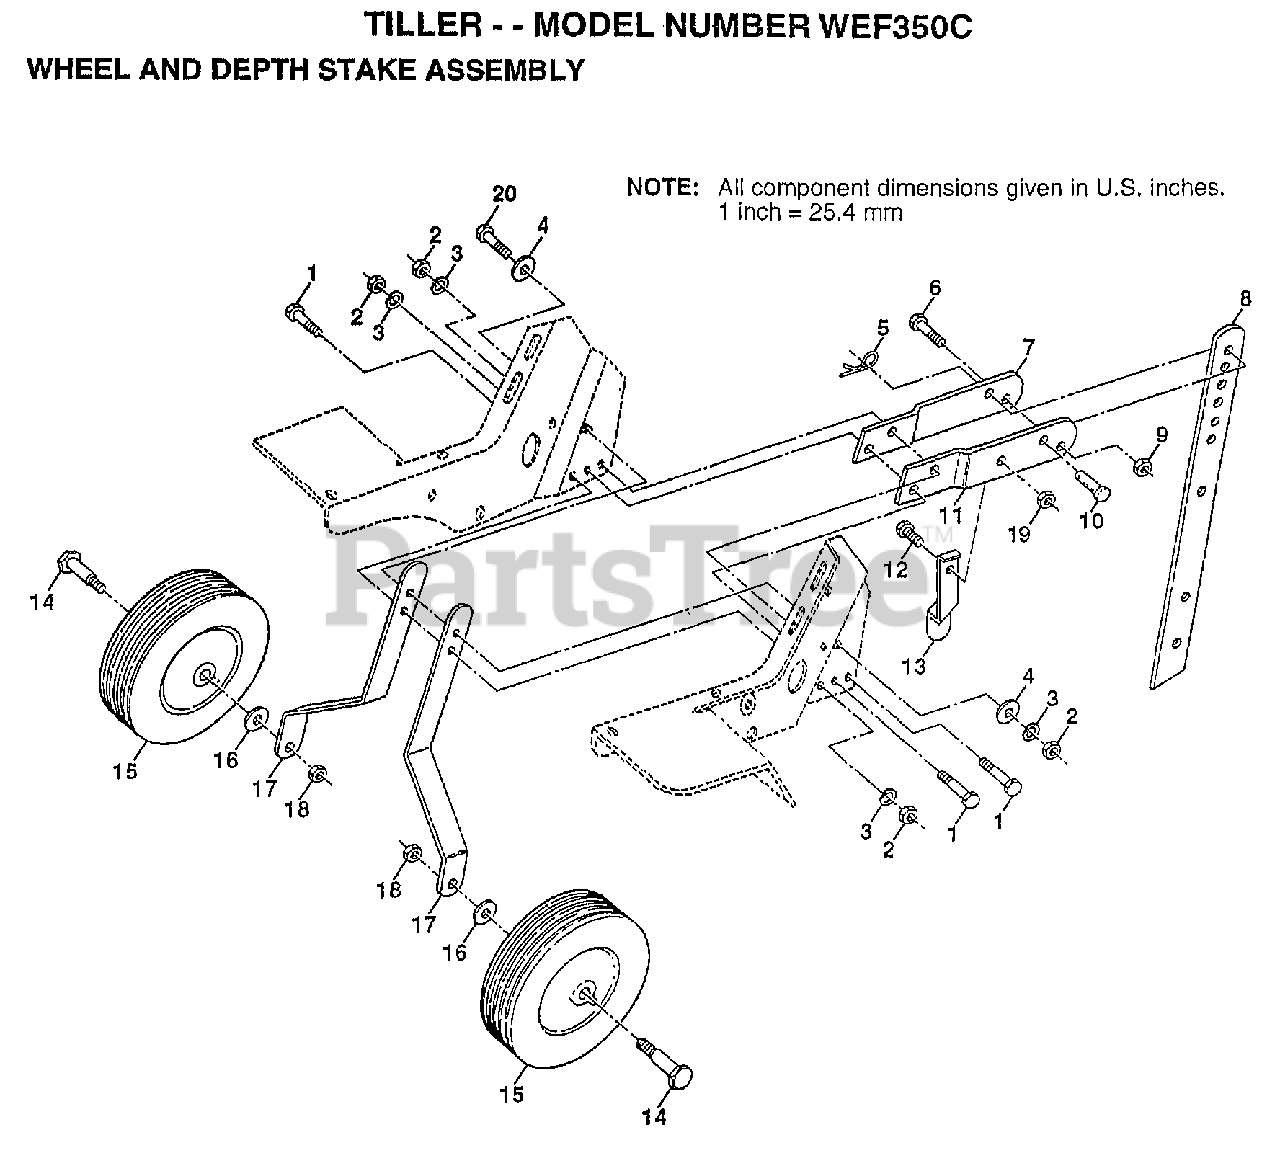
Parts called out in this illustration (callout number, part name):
2	NUT.HEX.5/16-18
3	LOCKWASHER
4	WASHER
5	SPRING.RETAINER
6	BOLT
7	STAKE.SUPT.TILLER
9	NUT
10	DRILLED RIVET RT
12	BOLT
13	STAKE SPRING CT
14	BOLT SHOULDER
15	WHEEL
16	WASHER
19	NUT
20	BOLT.HEX.5/16-1.5
